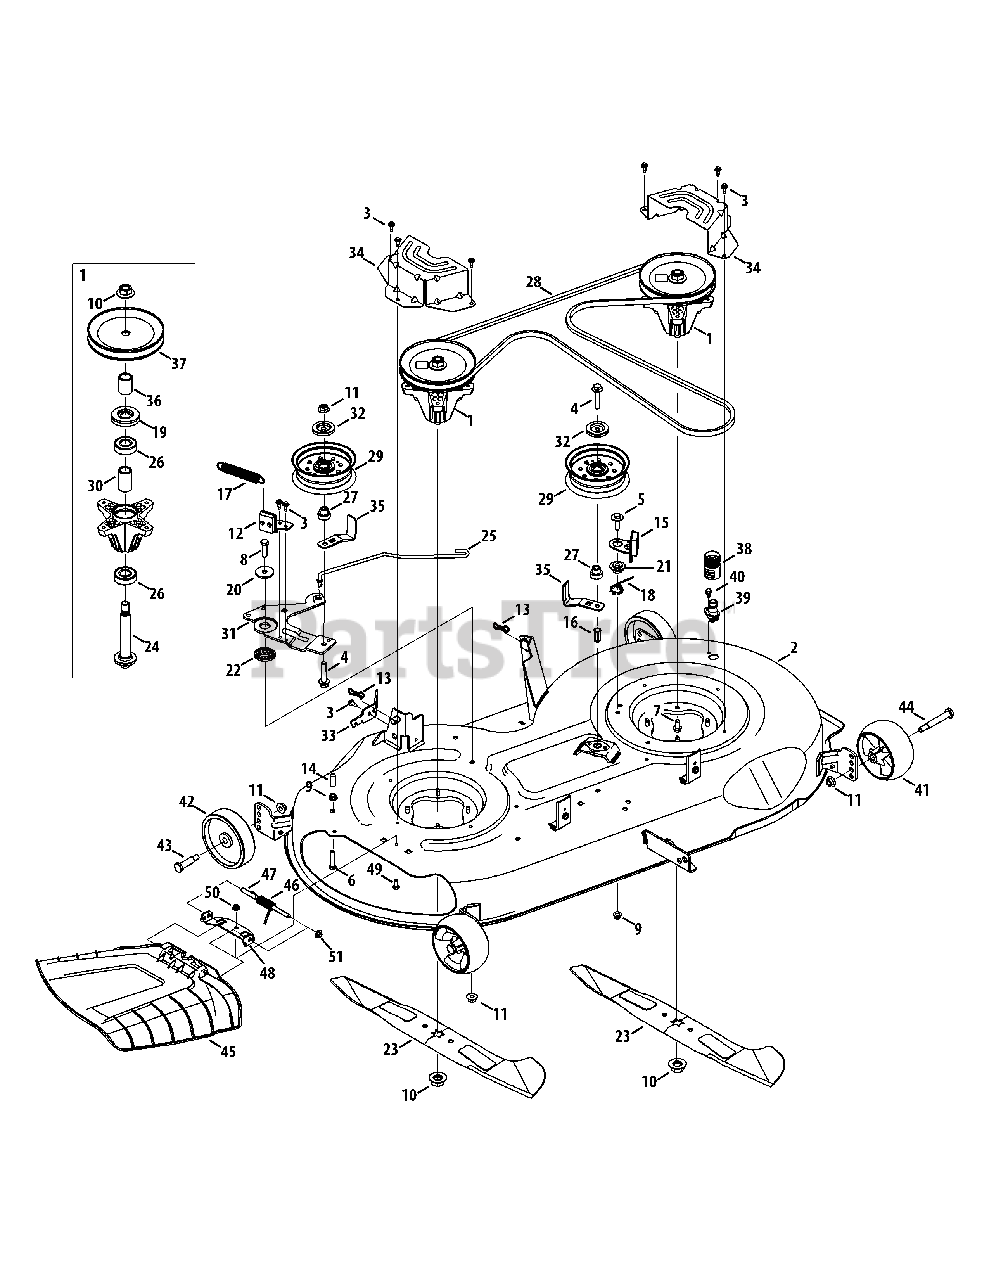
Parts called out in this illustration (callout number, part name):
1	Spindle Ass’y, Pulley, 6.93 Dia
2	Deck, 46"
3	Screw, M6-1 x .625
4	Hex Cap Screw, 3/8-16 x 2.00
5	Hex Cap Screw, 5/16-18 x 1.25
6	Hex Cap Screw, 5/16-18 x 1.50
7	Screw, Self-tapping, 5/16-18, 0.750,
8	Hex Cap Screw, 3/8-16 x 1.25
9	Nut, Flange Lock, 5/16-18, Nylon
10	Nut, Flange, 5/8-18
11	Flange Lock Nut, 3/8-16
12	Brake Assembly, Deck, RH
13	Bow-Tie Cotter Pin
14	Vinyl Cap, .29 x 1.00
15	Brake Assembly, Deck, LH
16	Rivet Nut, 3/8-16
17	Spring, Extension, .750 x .477
18	Spring, Torsion, LH Brake
19	Bearing Shield
20	Flat Washer, .39 x 1.5 x .134
21	Shoulder Spacer, .75 x .145
22	Shoulder Spacer, .854 x .191
23	Blade, Cut, 23.25" 2-In-1
24	Shaft, Spindle, 5.75
25	Rod, Brake, Deck
26	Bearing, Ball, .787id x 1.85 Od x .551
27	Shoulder Spacer, Idler
28	Belt, V-Type, A Sec x 108.3
29	Pulley, Idler, 4.50" Dia.
30	Spacer, .792 x 1.060 x 1.860
33	Bracket, Cable, PTO
35	Belt Keeper
36	Spacer, .800 x 1.10 x 1.470
37	Pulley, Deck, 6.74 Dia.
38	Coupler, Water
39	Deck Wash Nozzle
40	Shoulder Screw, 1/4-20 x 0.50
41	Wheel, Deck, 5.0 Dia. Ball
42	Wheel, Deck 5.0 x 1.38
43	Bolt, Shoulder, .496 x 1.525, 3/8-16
44	Bolt, Shoulder, .496 x 2.50, 3/8-16
45	Chute Deflector Assembly
46	Spring, Torsion, .440 ID x 1.75
49	Hex Cap Screw, 1/4-20 x .62
50	Nut, Flange Lock, 1/4-20, Nylon
51	Push Cap
